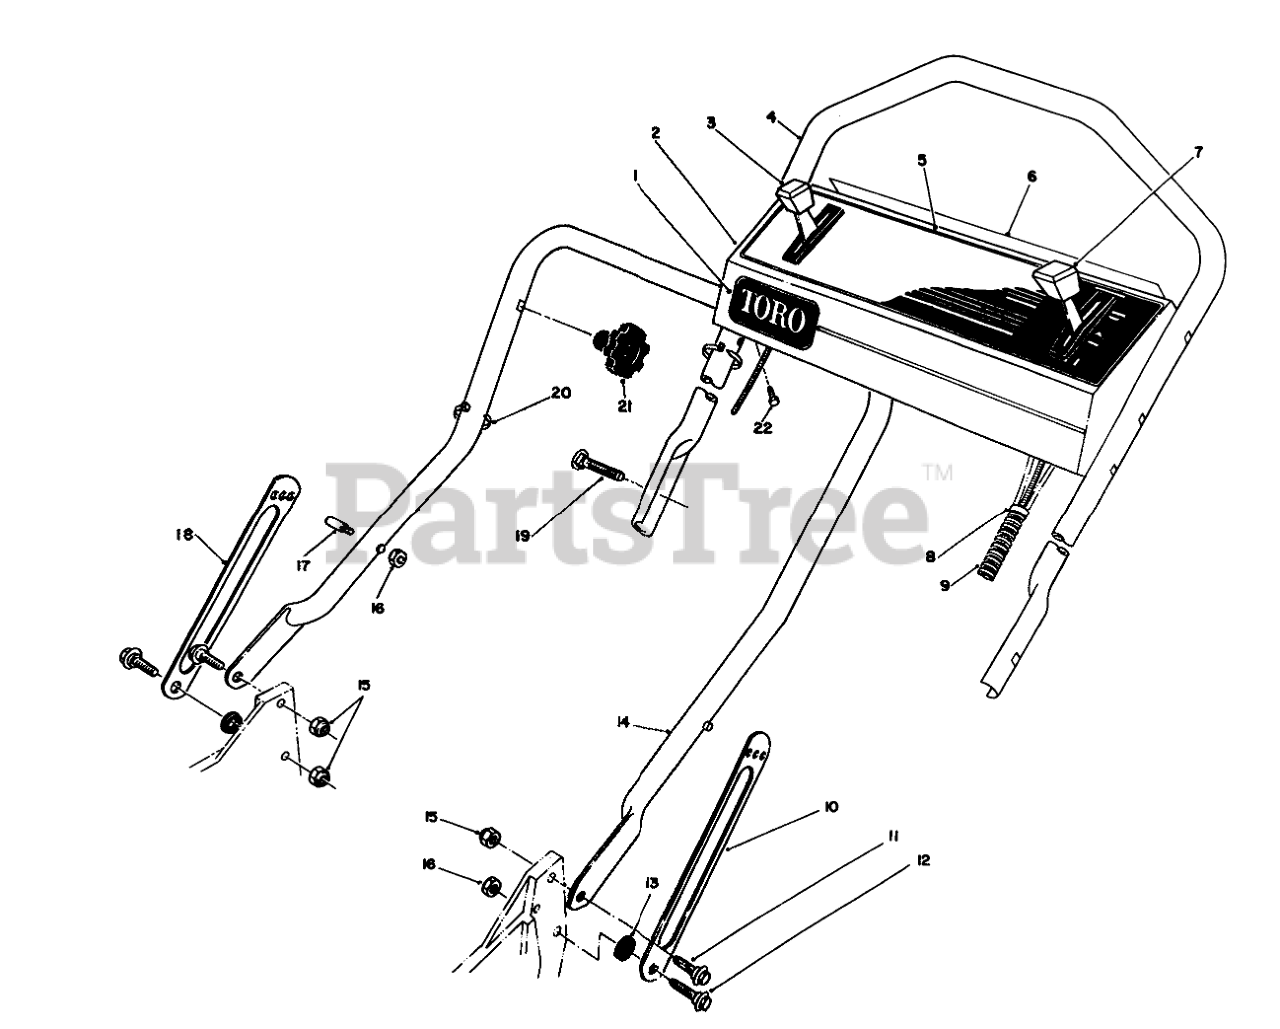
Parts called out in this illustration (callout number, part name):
1	DECAL - TORO
2	Panel-Control (Incl. Ref. #5)
3	Control-Ground Speed
4	UPPER HANDLE, PVC DIP
5	DECAL - INSTRUCTION
6	DECAL - PANEL, REAR
7	THROTTLE CONTROL
8	FITTING-RING
9	CONTROL CABLE COVER
10	LH HANDLE LATCH
11	SCREW-SHOULDER
12	SCREW-SHOULDER
13	SPACER
14	LOWER HANDLE ASM
15	NUT-LOCK, NI
16	NUT-LOCK, NI
17	HANDLE PIN
18	RH HANDLE LATCH
19	5/16-18 X 2 HNDLE SCREW
20	TIE-CABLE
22	SCREW-HWHTF
